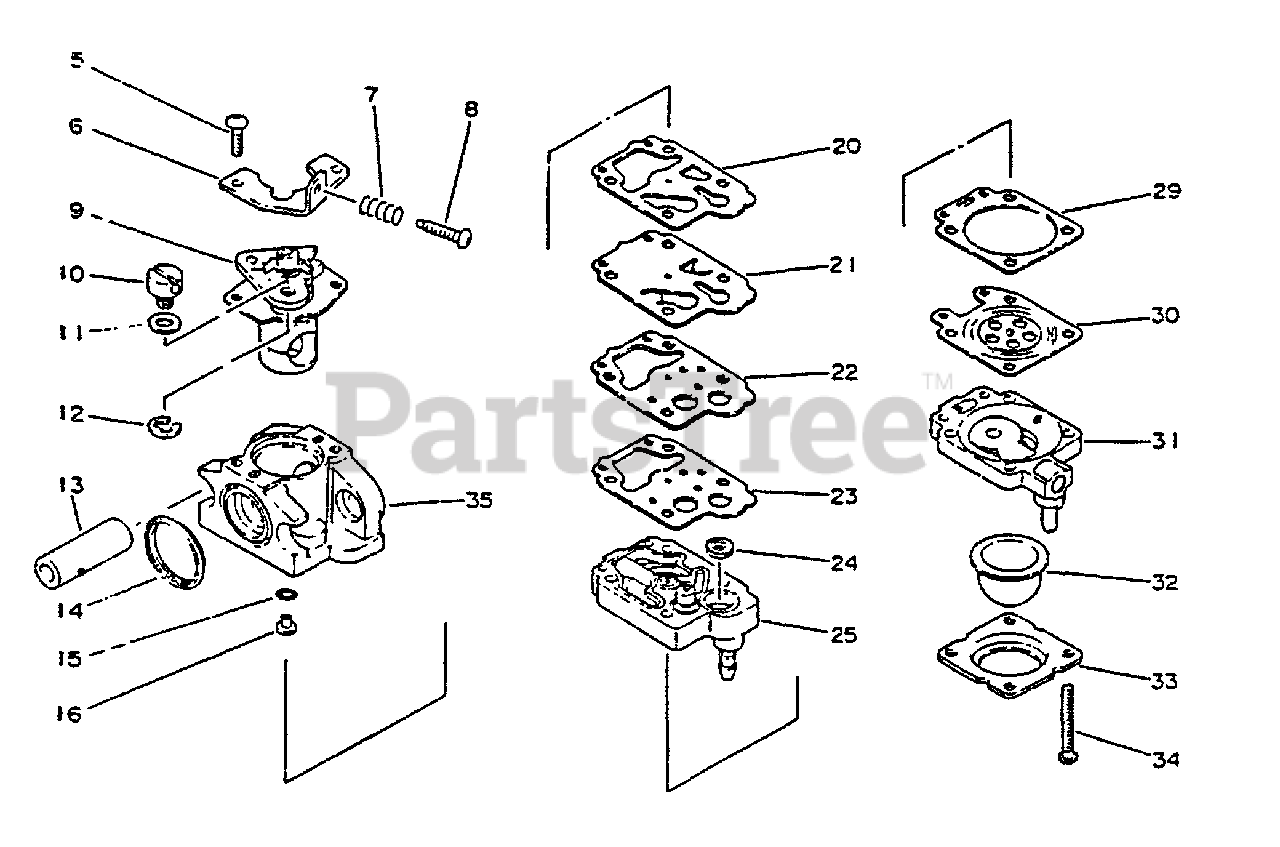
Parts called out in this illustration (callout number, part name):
6	BRACKET, THROTTLE CABLE
7	SPRING, IDLE ADJUST
8	SCREW, IDLE ADJUST
9	VALVE, THROTTLE
12	RING, RETAINING
13	SLEEVE, MOUNTING
14	SEAL
16	JET, MAIN
20	GASKET, PURGE
21	DIAPHRAGM, PURGE
22	PLATE, PUMP
23	GASKET, PLATE
24	STRAINER
25	BASE, PURGE
29	GASKET, METERING
30	DIAPHRAGM, METERING
31	BASE, PURGE
32	BULB, PURGE
33	RETAINER, PURGE BULB
35	BODY, CARBURETOR
